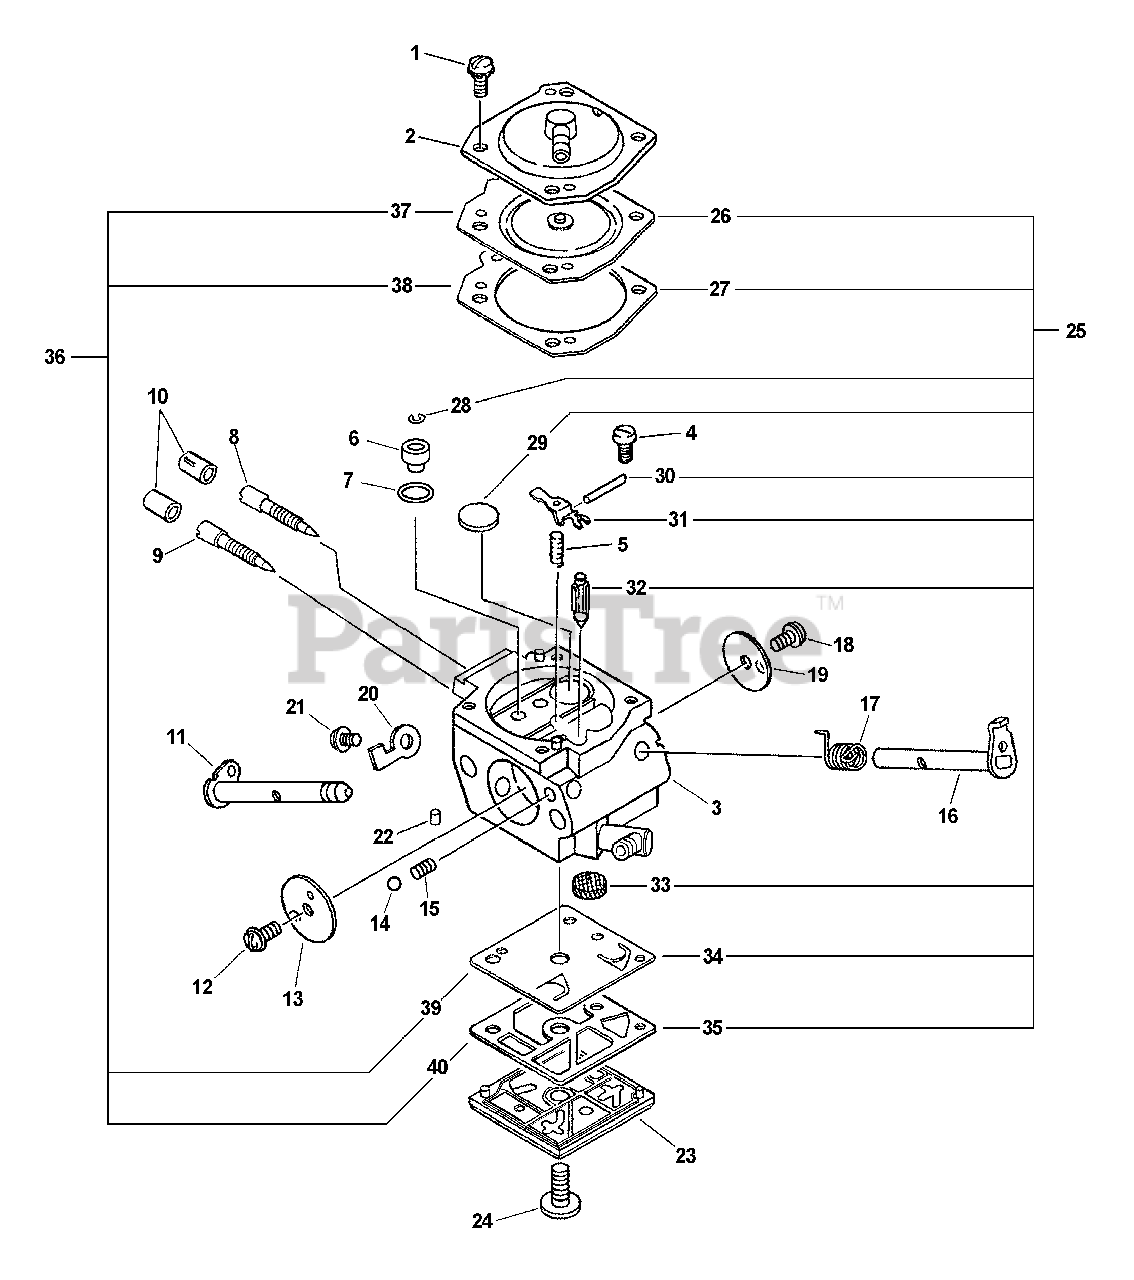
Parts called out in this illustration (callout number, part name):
2	COVER, METERING DIAPHRAGM
3	BODY, CARBURETOR
4	SCREW, METERING LEVER PIN
5	SPRING, METERING LEVER
6	JET
8	NEEDLE, MIXTURE
9	NEEDLE, HIGH SPEED
10	CAP, LIMITER
11	LEVER, CHOKE
13	VALVE, CHOKE
14	BALL, CHOKE FRICTION
16	SHAFT, THROTTLE
17	SPRING, THROTTLE RETURN
19	VALVE, THROTTLE
20	STOP, THROTTLE
22	PLUG, FRICTION
23	COVER, FUEL PUMP
25	REPAIR KIT
26	DIAPHRAGM, METERING
27	GASKET, DIAPHRAGM
28	RING, RETAINING
29	PLUG, WELCH
30	PIN, METERING LEVER
31	LEVER, METERING
32	VALVE, INLET NEEDLE
33	STRAINER
34	DIAPHRAGM, PUMP
35	GASKET, PUMP
36	GASKET / DIAPHRAGM KIT
37	DIAPHRAGM, METERING
38	GASKET, DIAPHRAGM
39	DIAPHRAGM, PUMP
40	GASKET, PUMP
